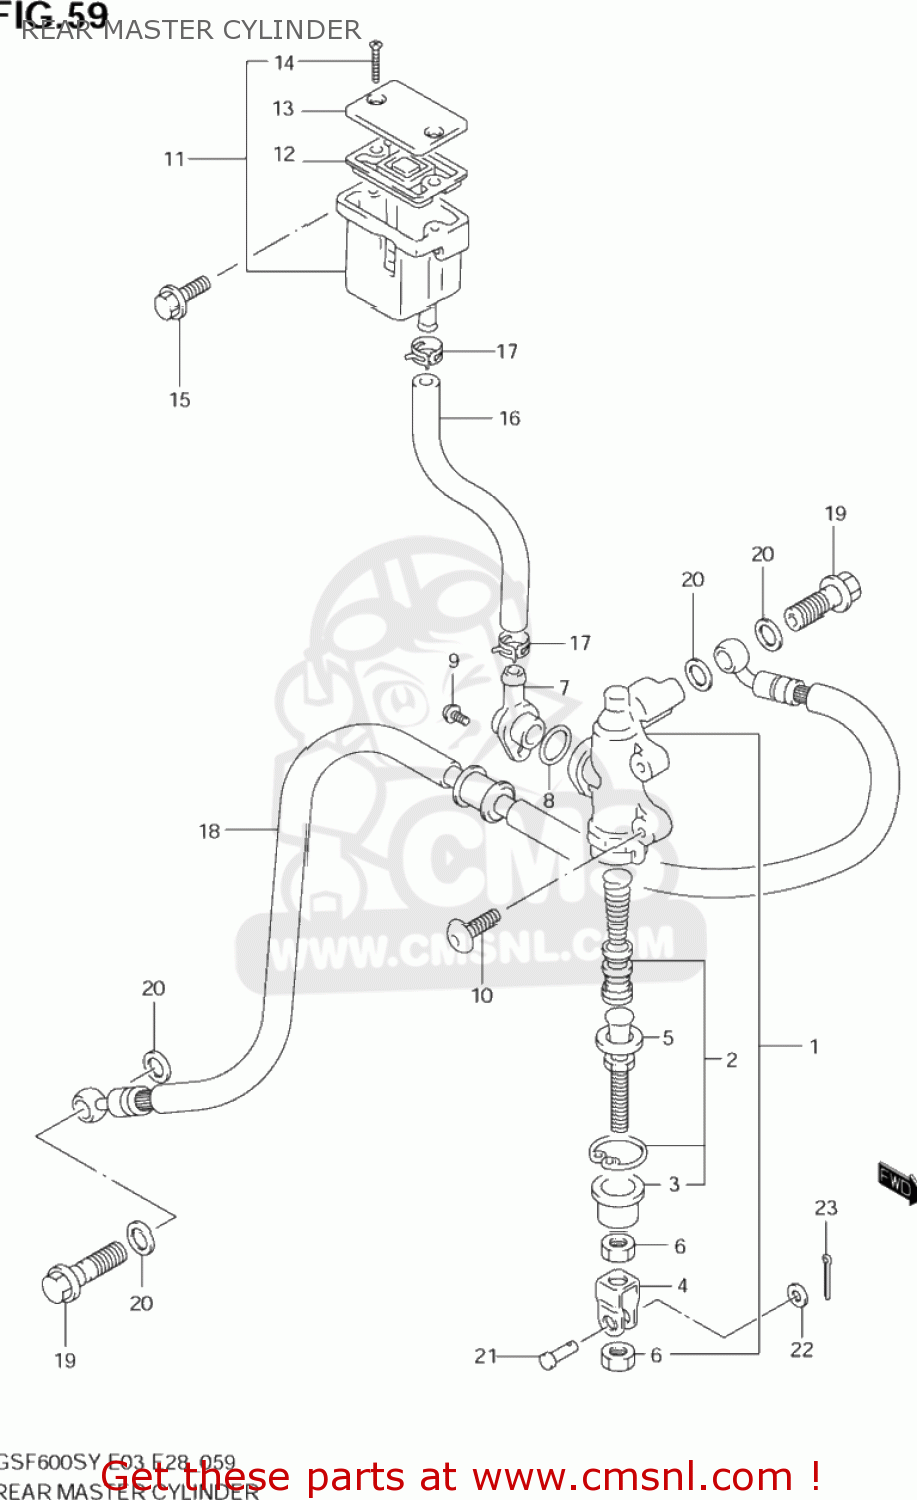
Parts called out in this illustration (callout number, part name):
1	CYLINDER ASSY,RR MASTER
2	PISTON/CUP SET
3	BOOT
4	YOKE
5	ROD,PUSH
6	NUT
7	CONNECTOR
8	O RING
9	SCREW
10	BOLT 8X20
11	TANK ASSY,RESERVOIR
12	DIAPHRAGM
13	CAP
14	SCREW
15	BOLT
16	HOSE,RR RESERVOIR TANK
17	CLIP
18	HOSE,REAR BRAKE
19	BOLT UNION
20	WASHER(10X15X1.5)
21	PIN
22	WASHER
23	PIN
